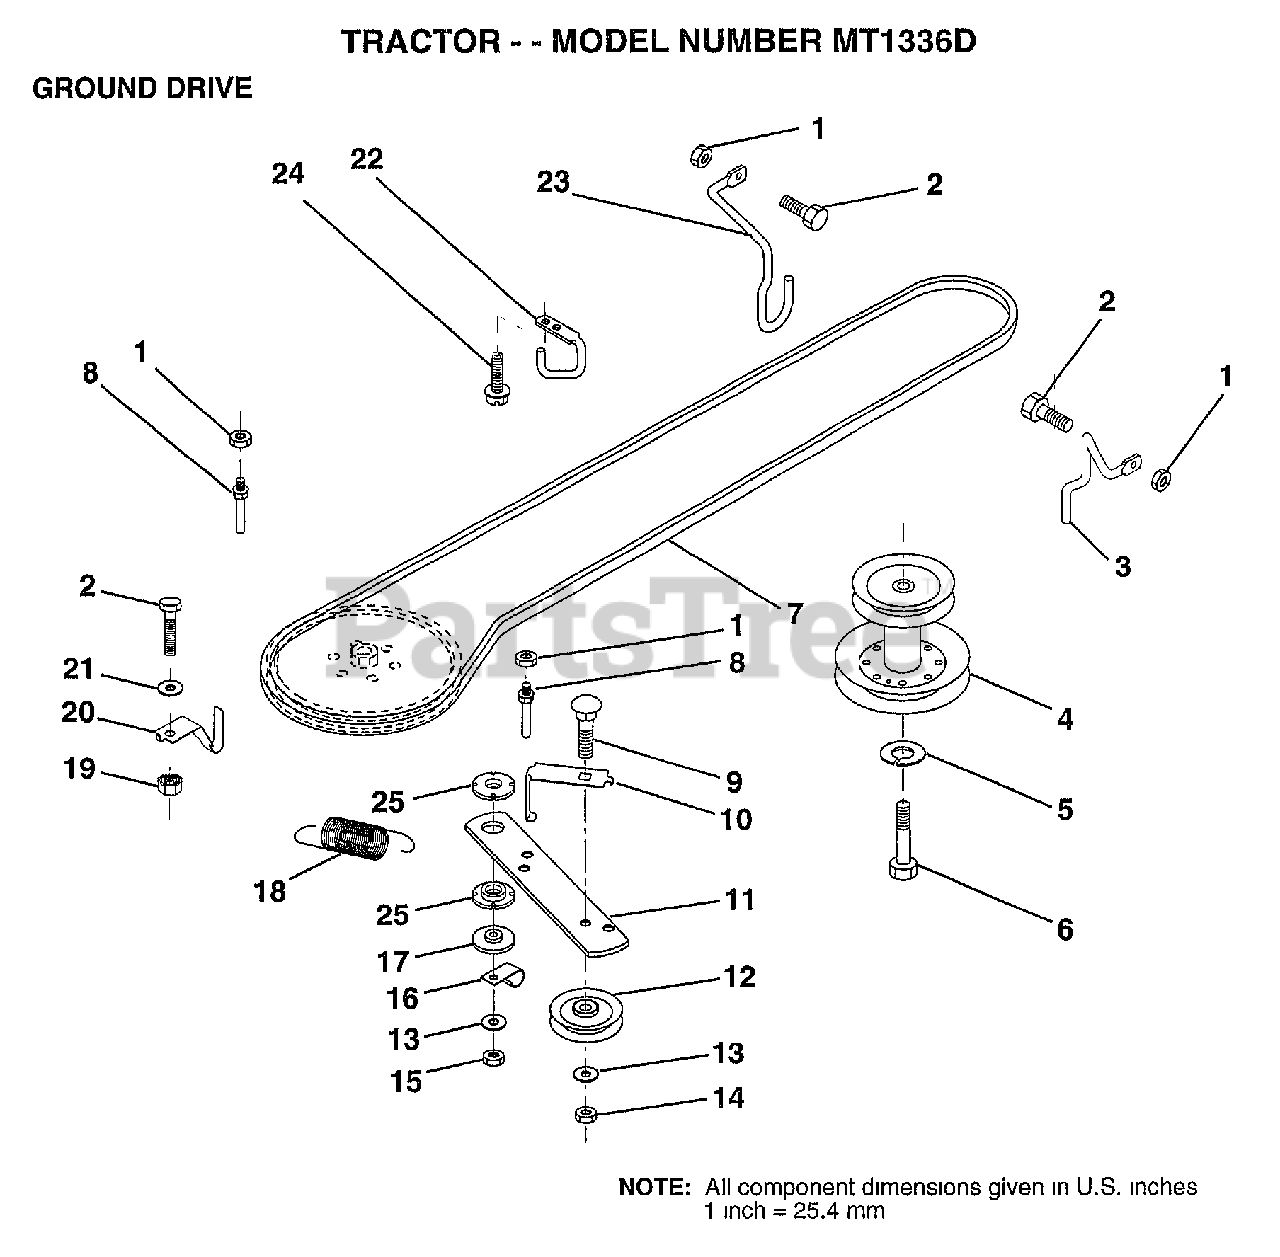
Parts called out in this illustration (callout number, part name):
2	BOLT
3	KEEPER RH
4	PULLEY.ENGINE.LR
5	LOCKWASHER
6	HEX BOLT
7	V BELT
8	"KEEPER,DRIVE BELT"
9	BOLT
10	"KEEP,IDLER DR BEL"
11	ARM-IDLER.DR.GRND
12	PULLEY.IDLER.FLAT
13	WASHER
14	LOCKNUT
16	"CLIP,INSULATOR"
17	SPACER
20	KEEPER.BELT.T/A
21	WASHER
22	"KEEPER,FRA DR BEL"
23	KEEPER MOWER LH
24	SCREW
25	BUSHING.NYLON
